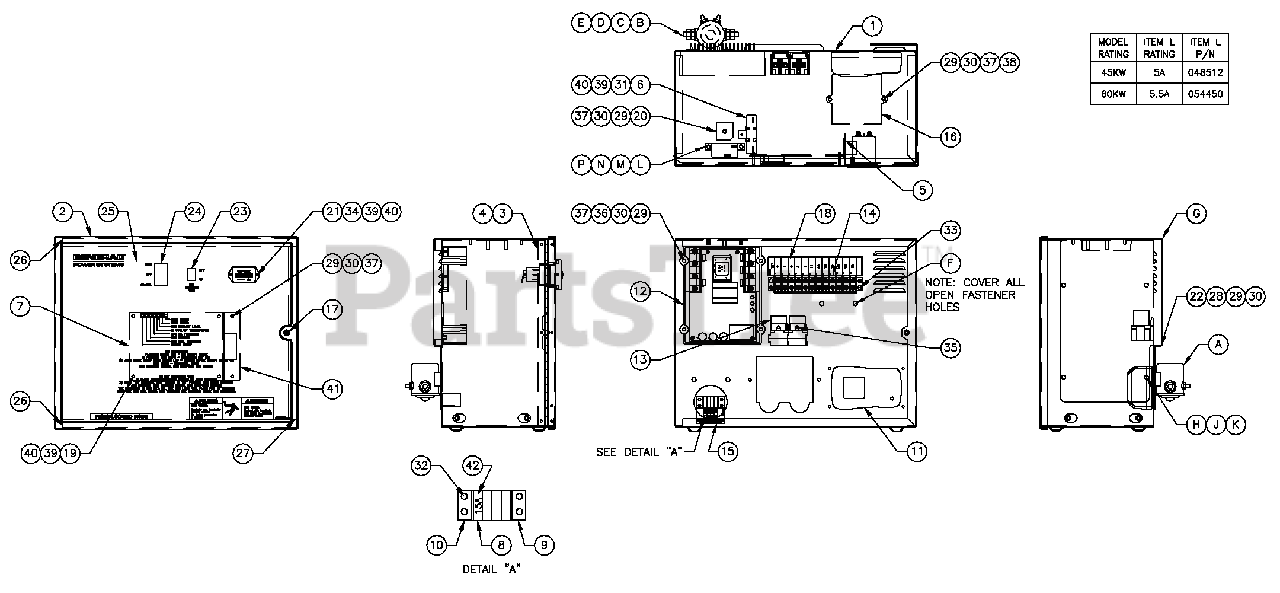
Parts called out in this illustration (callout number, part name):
1	ENCLHSB CONTROL PANEL
2	COVER CONTROL PANEL R-200B
3	HINGE CONTINUOUS H-PANEL
4	RIVET POP .125X .275SS
5	SCREW PPPH HI-LO #4-24 X 3/8
6	WASHER FLAT M3
7	ASSY PCB R-200C CNTRL 360 0 RPM
8	HOLDERFUSE WICKMANN 178.6150
9	ADPTR RH SIDE WICKMANN 178.6191
10	ADPTR LH SIDEWICKMANN 178.6192
11	BATC 13.4VDC 2.5A W/4POS PLUG
12	ASSY PCB HI-PWR VOLTAGE RGLTR
13	RELAY 12VDC C FORM W/DIODE
14	BLOCK TERM 20A12X 6 X1100V
15	DECAL CPL CNTPNL FUSES
16	ASSY PCB BOSCH GOV DRIVER
17	M5X0.8 CAPTIVE PANEL KNLD HD
18	DECAL CPL 39LTB1
19	SPACER 9.5H 3.2 ID
20	DIO BRIDGE25A 600V
21	HOUR METER 10-80VDC
22	PLATE HARNESS CLAMP
23	SWITCH RKRDPST 125V SPD
24	SWITCH RKRDPDTON-OFF-ON
25	DECAL CONTROL FLEX R-200B
26	SEAL COVER 3.18X12.7X382
27	SEAL COVER 3.18X12.7X283
28	SCREW HHPM M5-0.8X12
29	WASHER FLAT M5
30	WASHER LOCK M5
31	RES WW 15R 5% 25W QK CONN
32	SCREW PHTT M3.5-0.6 X 10
33	SCREW PHTT M3.5-0.6 X 16
34	SCREW PHM M3-0.5 X 10 BLACK
35	SCREW PHTT M4-0.7X 10ZYC
36	SCREW PPHM M5-0.8X 50ZNC
37	NUT HEXM5-0.8 G8YELCHR
38	SCREW PPHM M5-0.8X 30SS
39	WASHER LOCK M3
40	NUT HEXM3-0.5 G8YELCHR
41	SUPPORT ANGLE PCB
42	FUSE ATO TYPE 15 AMP (BLUE)
A	RELAY SOLENOID 12VDC PNL MNT
B	SCREW HHC 1/4-20X 3/4G5
C	WASHER FLAT 1/4-M6 ZINC
D	WASHER LOCK M6-1/4
E	NUT HEX 1/4-20 STEEL
F	SEAL WEATHER.45"DIA
G	COVER CONTROL PANEL SIDE
H	SCREW PPHM M5-0.8X 12ZNC
J	WASHER LOCK M5
K	WASHER FLAT M5
L	DPEBREAKER
M	WASHER FLAT M3
N	WASHER LOCK M3
P	NUT HEXM3-0.5 G8YELCHR
